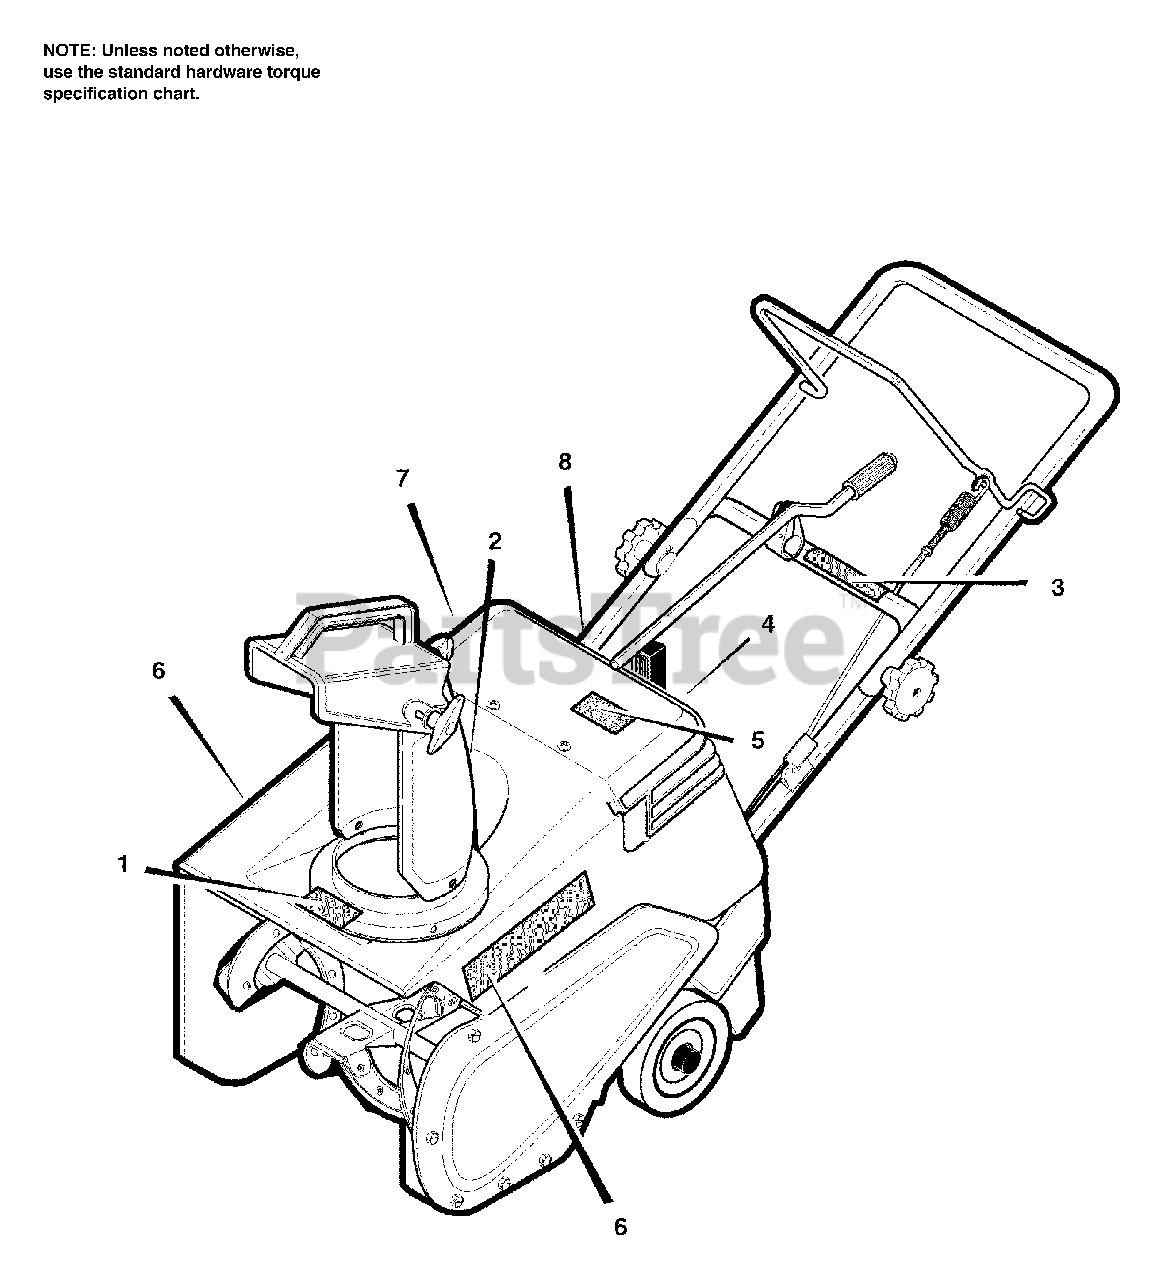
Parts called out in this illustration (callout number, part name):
1	DECAL, DANGER AUGER
2	DECAL, DANGER CHUTE
3	DECAL, AUGER CONTROL
4	DECAL, CONTROL PANEL
5	DECAL, HOT MUFFLER
6	DECAL, Husqvarna 5/21
7	DECAL, EPA
8	DECAL, 521SSE
8	DECAL, 521SSR
